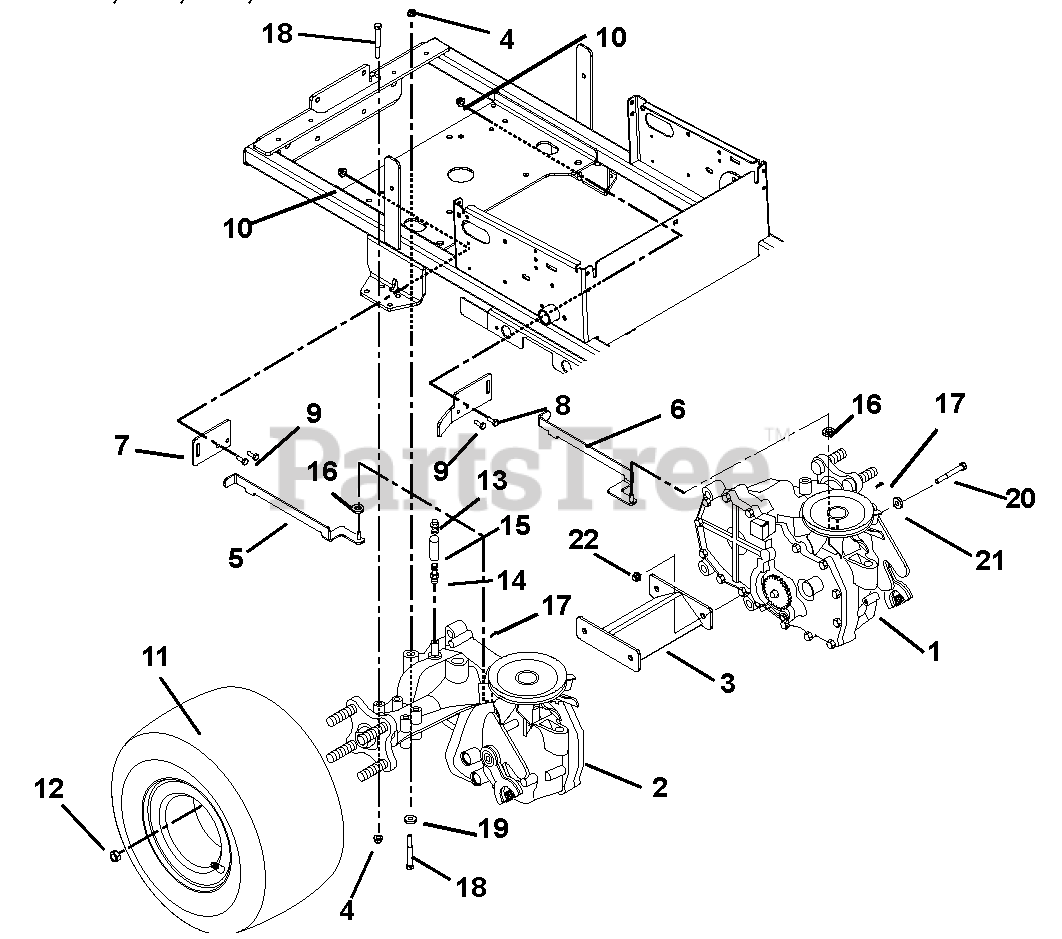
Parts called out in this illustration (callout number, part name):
1	EZT, Left Hand Transaxle-Hydrogear (For service please contact Hydro-Gear) (102, 104, 106, 116)
2	EZT, Right Hand Transaxle-Hydrogear (For service please contact Hydro-Gear) (102, 104, 106, 116)
3	Weldment, Transaxle Support
4	Nut 5/16-18 Flange Nyloc
5	Weldment, Dump Valve (RH)
6	Weldment, Dump Valve (LH)
7	Bracket, Dump Valve
8	Bracket, Dump Valve/Clutch Stop (104, 106, 116)
9	Bolt-Hex .25-20 x .75 Grade 5
10	Nut, Locking Nylon .250-20
11	Assembly, Tire 18 x 8.5-8 (104, 106, 116)
12	Nut, Lug .50-20
13	Cap, Vent .50
14	Fitting, Straight .50
15	Hose, Vent
16	Washer-Flat-Steel .265 x .50 x .102
17	Pin-Hair-Internal .06 x .18 x .77
18	Bolt, Hex .31-18 x 2.75
19	Washer, Flat Steel .328 x .87 x .179
20	Bolt, Hex .38-16 x 2.50 Grade 5
21	Washer, Flat Steel .406 x 1.00 x .188
22	Nut, .38-16 Nyloc Flange
